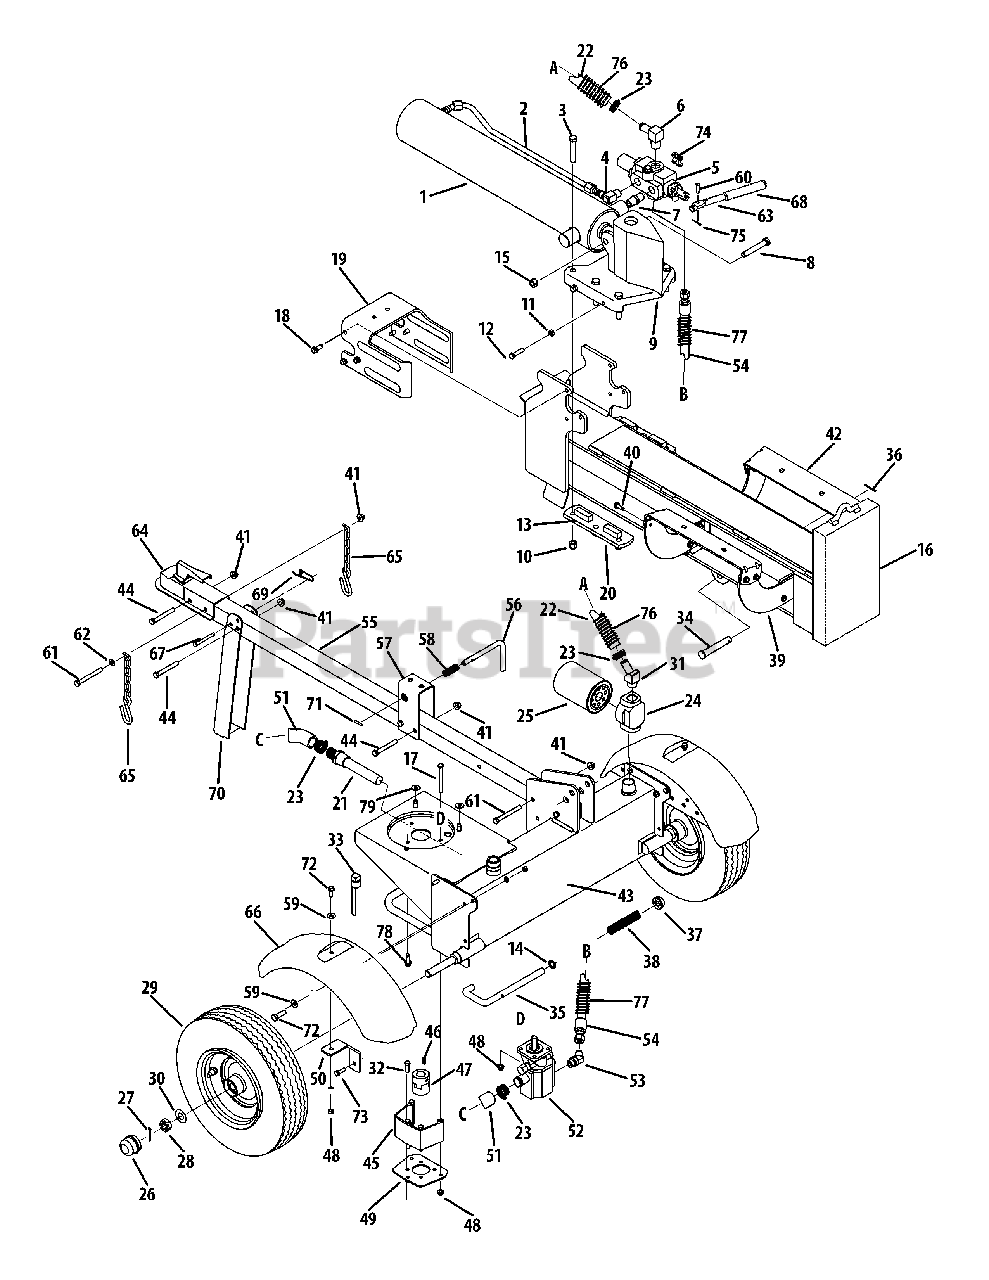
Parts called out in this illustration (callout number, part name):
1	Hydraulic Cylinder
1	Kit Seal 4.5" for XINGHUI cylinder
1	Kit Seal 4.5" for ENERGY cylinder
2	Hydraulic Tube
3	Hex Cap Screw, 1/2-20 x 2.75
4	90 Degree Solid Adapter
5	Control Valve
6	Return Elbow
7	Nipple Pipe, 1/2-14
8	Hex Cap Screw, 1/2-13 x 3.25
9	Wedge Assembly
10	Hex Lock Nut, 1/2-20
11	Hex Jam Nut, 3/8-24
12	Hex Cap Screw, 3/8-24 x 1.5
13	Adjustable Gib
14	Flat Washer, .635 x.93 x.06
15	Hex Lock Nut, 1/2-13
17	Hex Screw, 5/16-18 x 3.25
18	Hex Washer Screw, 3/8-16 x 1.0
19	Dislodger Bracket
20	Back Plate
21	Inlet Filter
22	Return Hose, 3.4" ID x 44" Lg.
23	Hose Clamp, 5.8"
24	Filter Housing
25	Oil Filter
27	Cotter Pin
28	Slotted Nut, 3/4-16
29	Wheel Assembly
30	Flat Washer, .760 ID x.500 OD
31	Adapter, 3/4-14
32	Hex Screw, 5/16-18 x 1.00
33	Vented Dipstick
34	Clevis Pin
36	Cotter Pin
38	Compression Spring
39	Log Tray Bracket
40	Hex Washer Screw, 5/16-18 x .750
41	Flange Lock Nut, 3/8-16
43	Frame Assembly
44	Hex Bolt, 3/8-16 x 3
45	Coupling Shield
46	Square Key, 3/16 x.75
47	Coupling, Logsplitter
48	Flange Lock Nut, 5/16-18
49	Rear Coupling Support Bracket
50	Fender Mounting Bracket
53	45 Degree Elbow Fitting
54	High Pressure Hydraulic Hose
55	Tongue Assembly
56	Latch Rod
58	Compression Spring
59	Flat Washer
60	Clevis Pin
61	Hex Cap Screw, 3/8-16 x 3.50
62	Flat Washer, .375 x.738 x.063
63	Hydraulic Valve Control
64	Hitch Coupling Assembly
67	Clevis Pin
69	Spring Pin
71	Spiral Pin
72	TT Screw, 5/16-18 x 0.875
73	TT Screw, 5/16-18 x 1.00
74	Valve Handle Link
75	Cotter Pin
76	Hose Guard, 44"
77	Hose Guard, 48"
78	Sems Screw, 3/8-16 x 1.250
79	Flat Washer, .407 x .812 x .135
